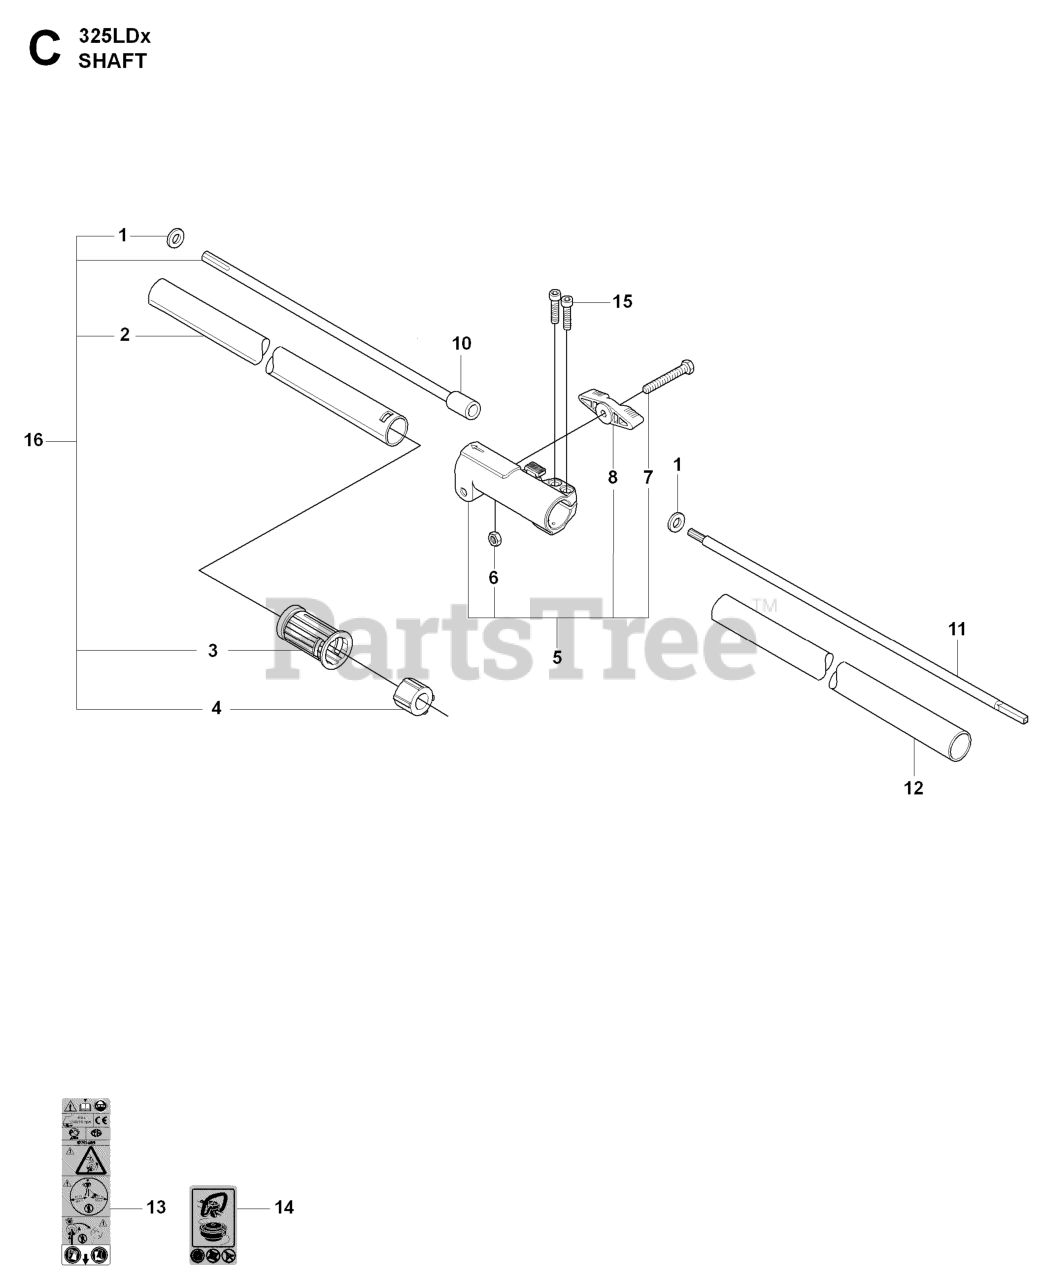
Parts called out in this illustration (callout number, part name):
3	PLUG
4	BUSHING
5	CLAMPING SLEEVE
7	BOLT FLANGE
10	SHAFT LOWER
13	RP WARNING DECAL
14	DECAL WARNING "NO BLADES"
14	ANTIVIBRATION ELEMENT
16	TUBE
